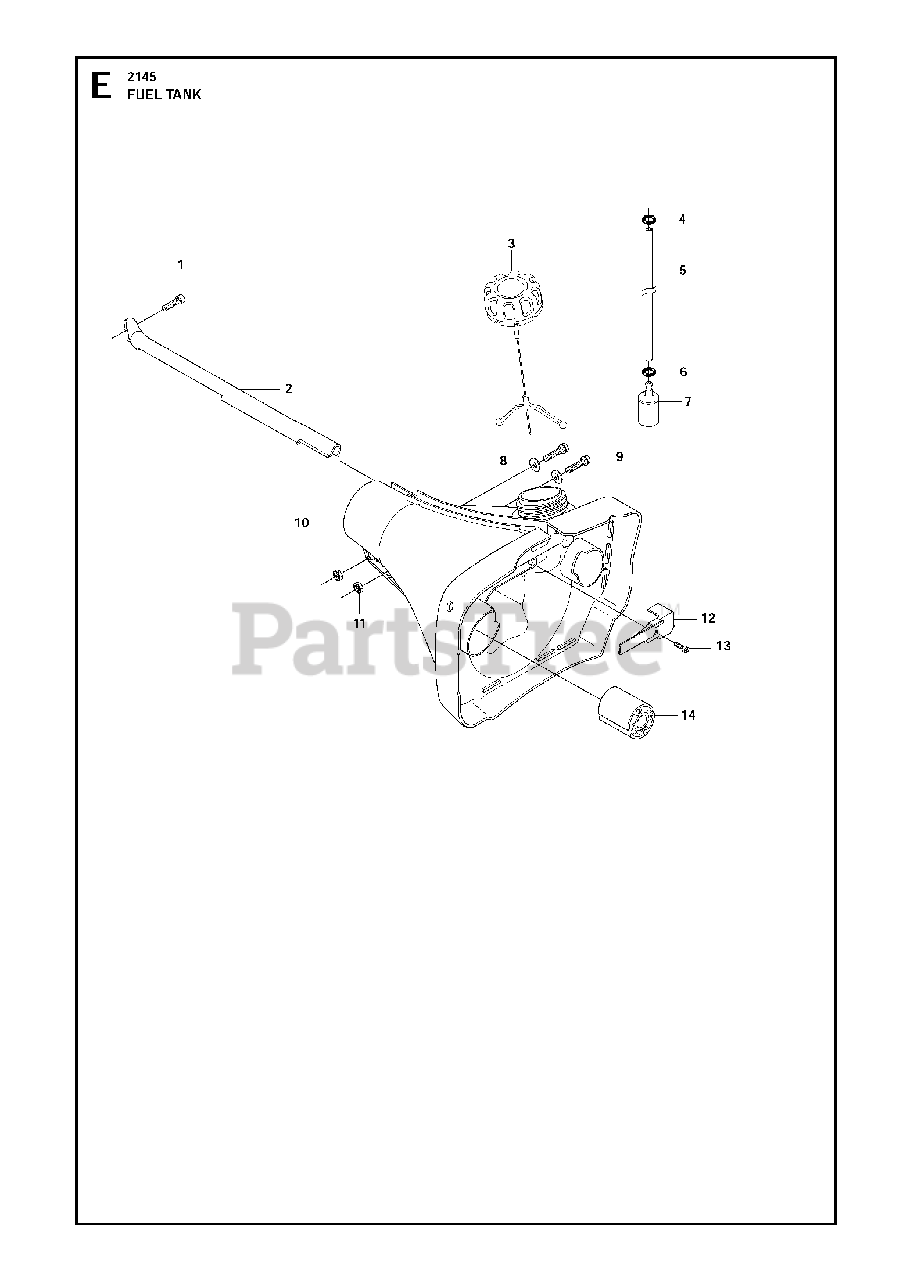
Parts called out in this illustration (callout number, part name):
2	TUBE (FC,FCS)
2	TUBE (BC)
3	%WINTER TANK CAP
5	FUEL HOSE
7	FUEL FILTER
8	WASHER 5.3X12
10	TANK UNIT
14	%BELLOWS
